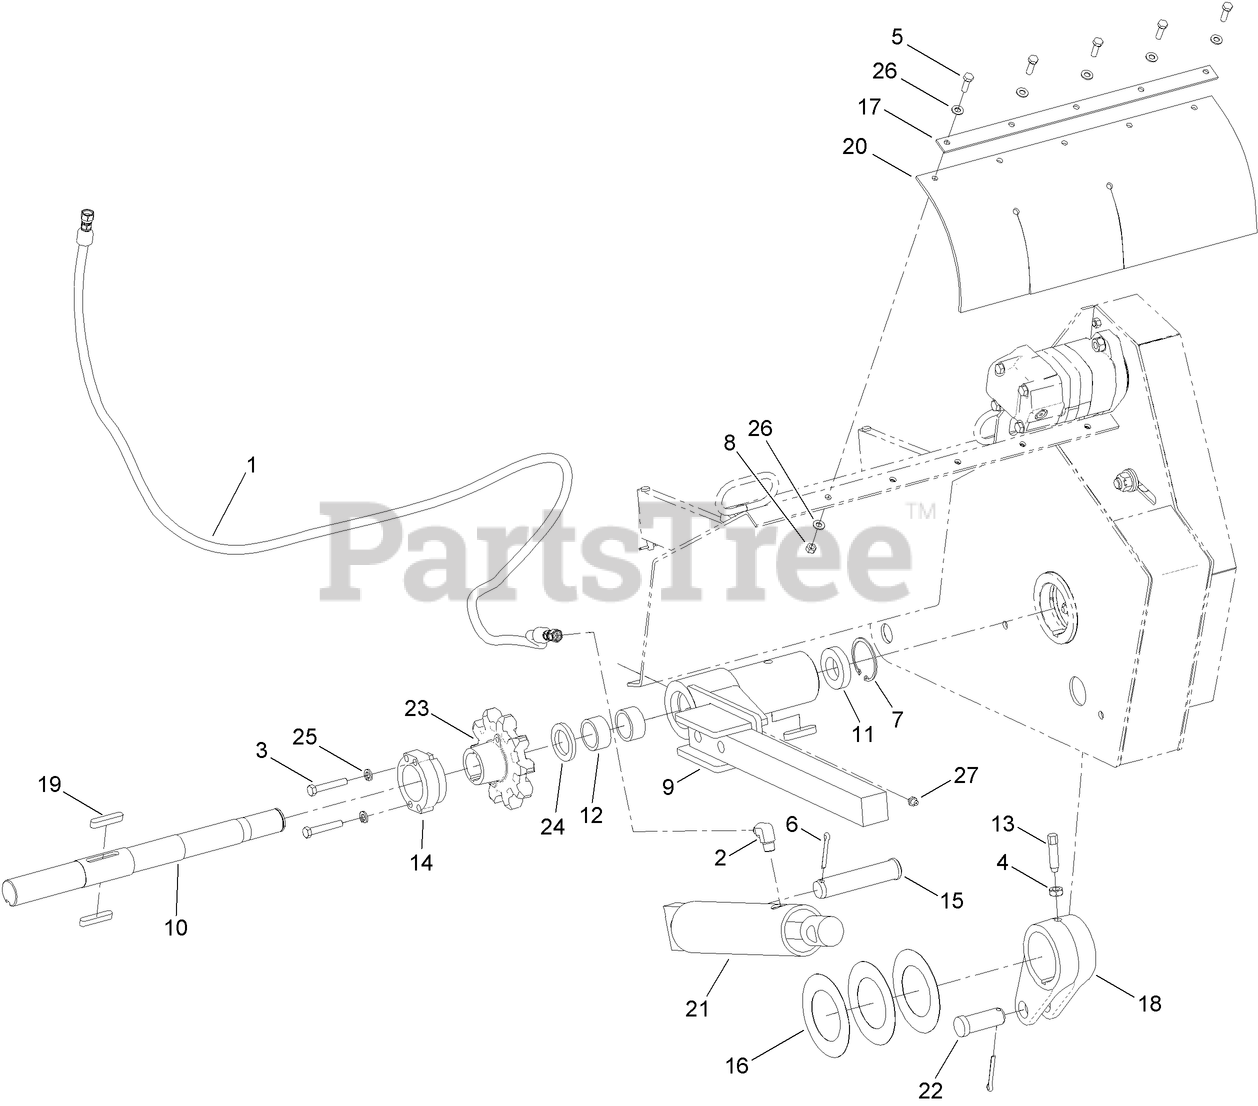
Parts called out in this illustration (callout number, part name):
1	HOSE ASM
2	FITTING-ELBOW, 90 DEG
3	SCREW-HH
5	SCREW-HH
6	PIN-COTTER
7	RING-SNAP, INTERNAL
8	NUT-LOCK, CONE
9	MOUNT-BOOM
10	SHAFT-DRIVE, TRENCHER
11	BEARING
12	BEARING-NEEDLE
13	SCREW-SET, DOG POINT
17	STRIP-BACK
18	CRANK (BOOM CYLINDER)
20	FLAP-DIRT
21	HYD CYLINDER ASM
22	PIN-CLEVIS
23	SPROCKET
24	SEAL-OIL
25	WASHER-LOCK
26	WASHER-PLAIN
27	FITTING-GREASE
